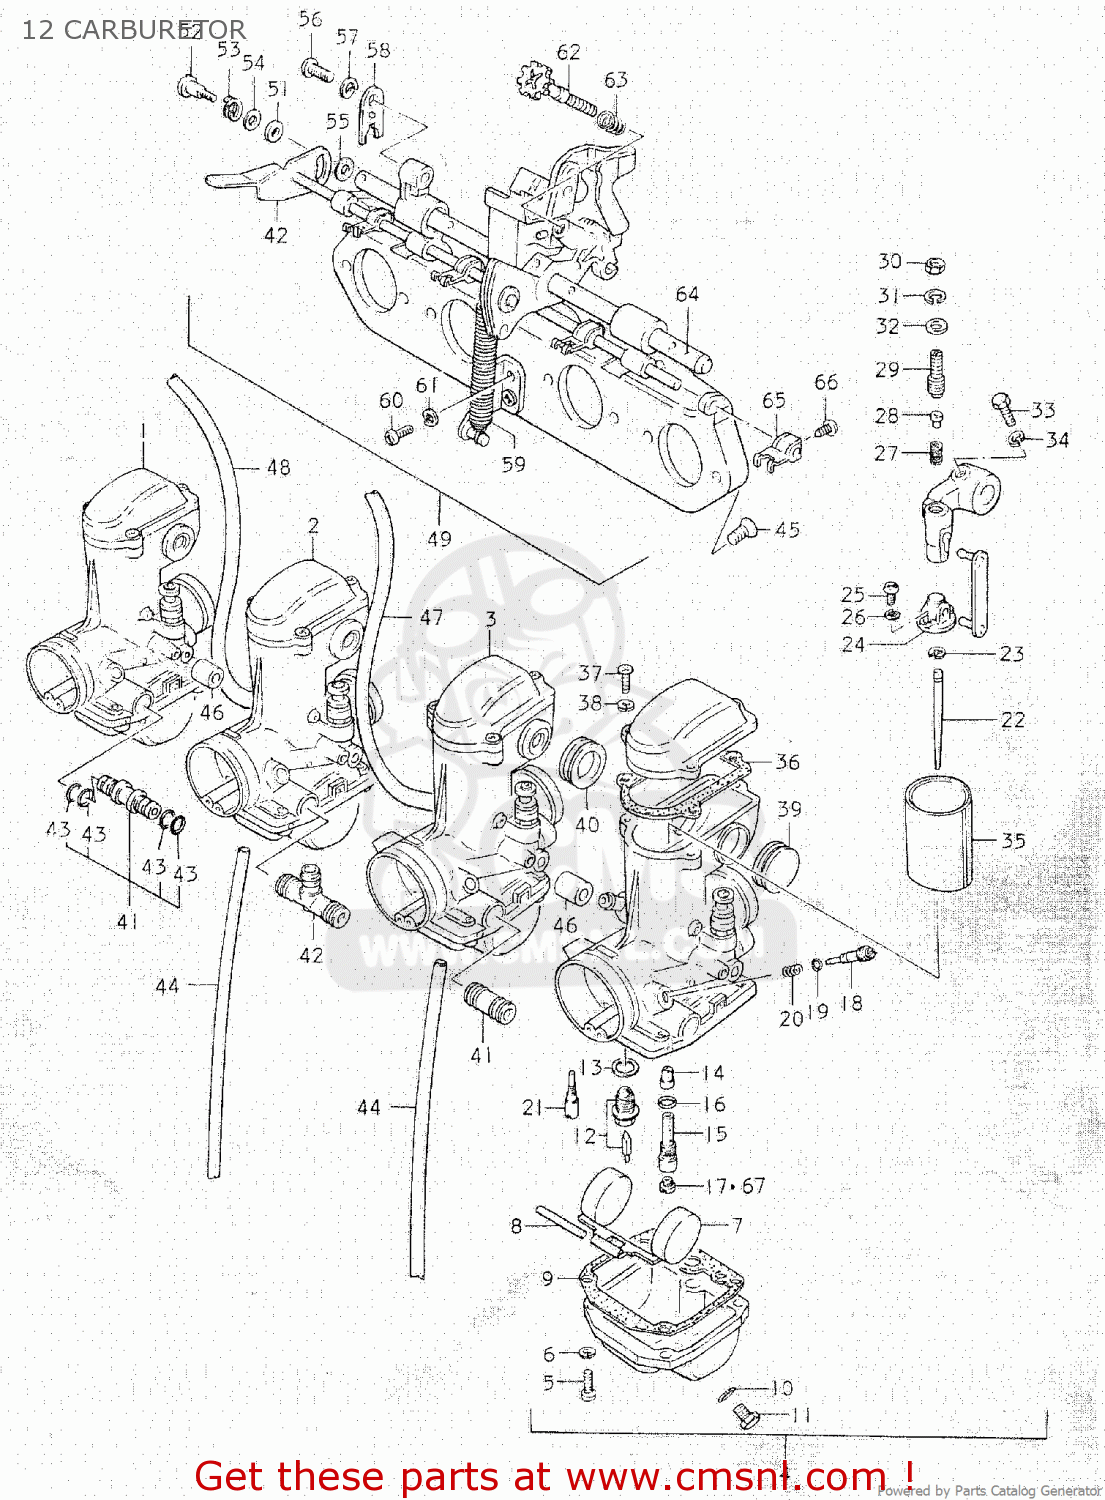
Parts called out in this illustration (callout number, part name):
1	CARBURETOR ASSEMBLY
2	CARBURETOR ASSEMBLY
3	CARBURETOR ASSEMBLY
4	CARBURETOR ASSEMBLY
5	SCREW
6	LOCK WASHER
7	FLOAT
8	PIN,FLOAT
9	GASKET,FLOAT CHAMBER (NAS)
10	O RING
11	SCREW
12	VALVE ASSEMBLY,NEEDLE
13	GASKET,VALVE SEAT (NAS)
14	JET,NEEDLE
15	PIPE,BLEEDER
16	O RING
17	JET
18	SCREW,PILOT AIR
19	O RING
20	SPRING
21	JET
22	NEEDLE JET
23	E-RING
24	CONNECTOR
25	SCREW
26	LOCK WASHER
27	SPRING
28	PIN,CARBURETOR
29	SCREW
30	NUT
31	LOCK WASHER
32	WASHER
33	BOLT
34	LOCK WASHER
35	VALVE,THROTTLE
36	GASKET (NAS)
37	SCREW
38	LOCK WASHER
39	PIPE,DELIVERY
40	SEAL
41	NIPPLE
42	NIPPLE
43	O-RING
44	HOSE
45	SCREW
46	HOSE
47	HOSE
48	HOSE 4.5X8X390
49	CARBURETOR ASSEMBLY
51	WASHER
52	SCREW,STARTER LEVER
53	SPRING
54	WASHER,STARTER SHAFT
55	WASHER,STARTER SHAFT
56	SCREW
57	LOCK WASHER
58	GASKET
59	SPRING,THROTTLE RETURN
60	SCREW
61	LOCK WASHER
62	ADJUSTER
63	SPRING,THROTTLE SCREW
64	SHAFT ASSEMBLY
65	LEVER, STARTER
66	SCREW
67	JET
